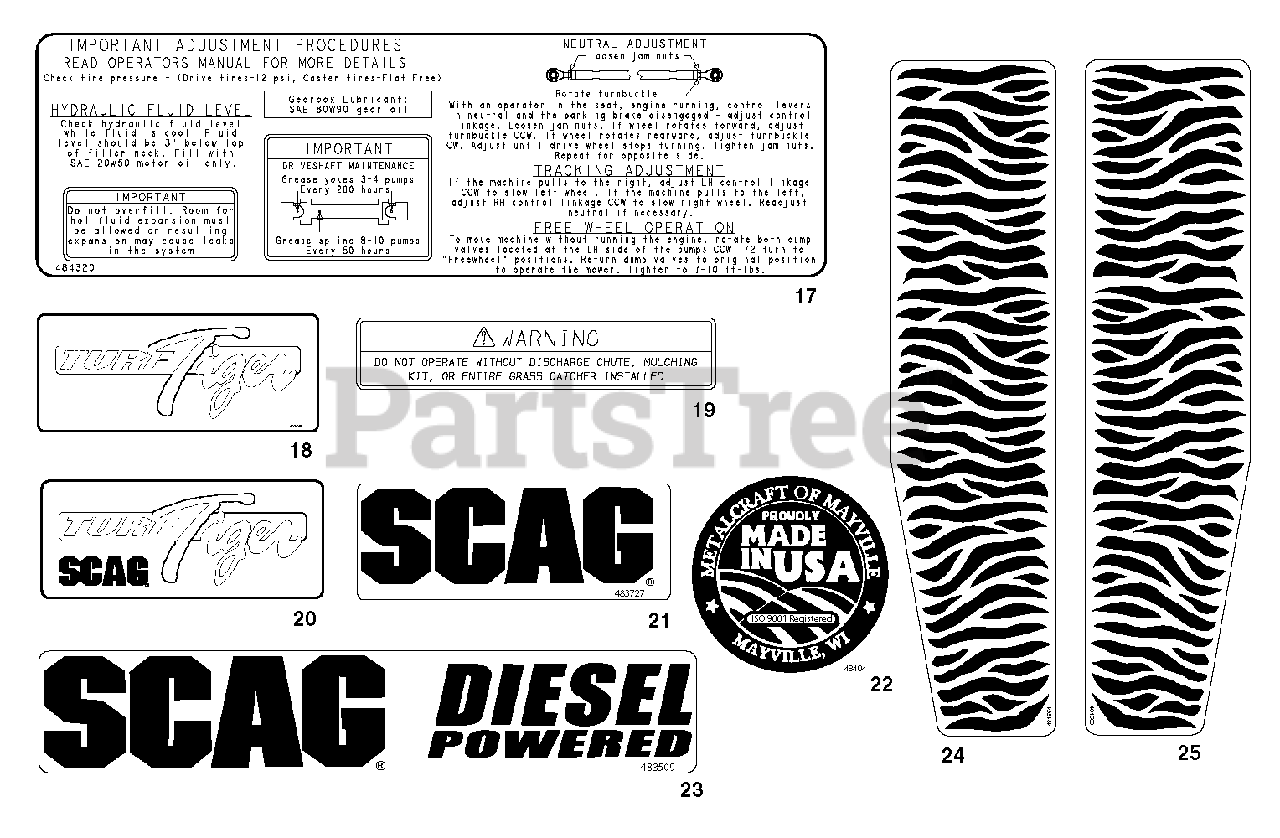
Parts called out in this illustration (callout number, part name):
17	Decal, Checks and Adjustments
18	Decal, Turf Tiger
19	Decal, Warning
20	Decal, Turf Tiger
21	Decal, Scag Logo
22	Decal, Metalcraft-Made In USA
23	Decal, Scag Diesel Powered
24	Decal, Stripes-RH
25	Decal, Stripes-LH
